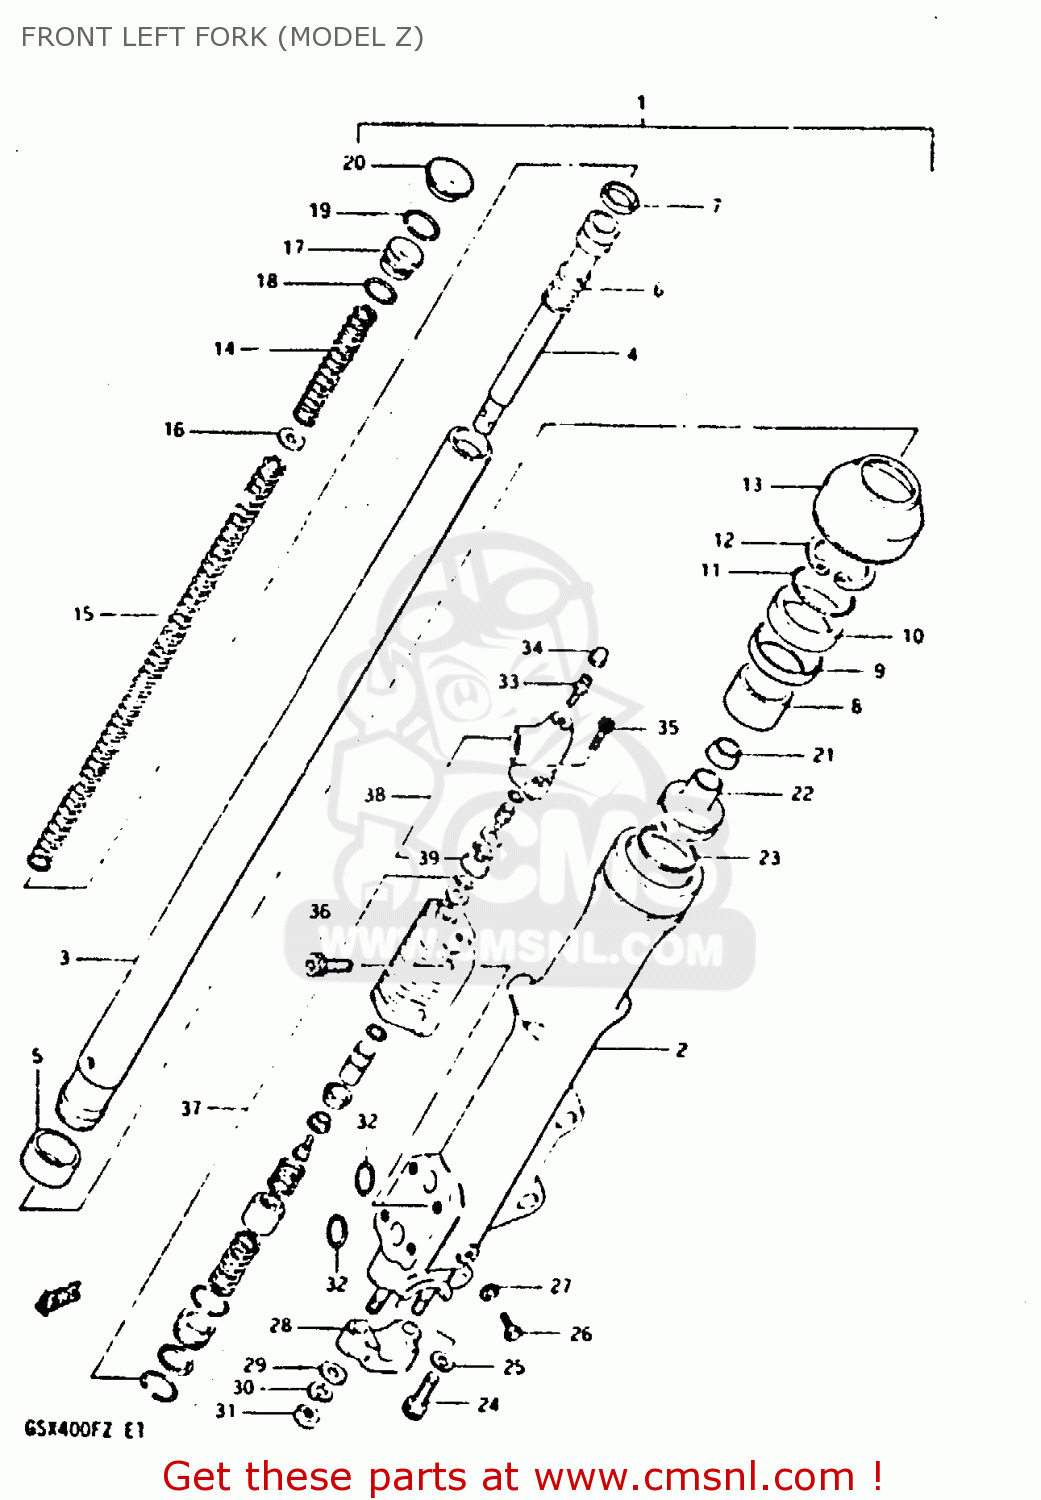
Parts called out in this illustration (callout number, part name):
1	FRONT LH DAMPER
2	OUTER TUBE LH
3	INNER TUBE
4	CYLINDER, LH
5	BUSH
6	SPRING,REBOUND
7	RING,PISTON
8	BUSH,GUIDE
9	SPACER,OIL SEAL
10	OIL SEAL,FRONT FORK
11	RING,BACKUP
12	RING,OIL SEAL STOPPER
13	DUST SEAL
14	SPRING A
15	SPRING (B)
16	SEAT,SPRING
17	SEAT,SPRING
18	O RING
19	RING,STOPPER
20	CAP
21	VALVE,OIL LOCK PIEACE
22	PIECE,OIL LOCK
23	RING, PISTON
24	BOLT(8X27)
25	GASKET (NAS)
26	BOLT
27	GASKET,DRAIN,PLUG (NAS)
28	HOLDER,AXLE
29	WASHER
30	LOCK WASHER
31	NUT
32	O RING,FR FORK
33	BREATHER
34	CAP
35	BOLT
36	BOLT
37	MODULATOR VALVE SET
38	MODULATOR PARTS SET,FRONT
39	SEPARATOR,FRONT FORK MODULATOR
